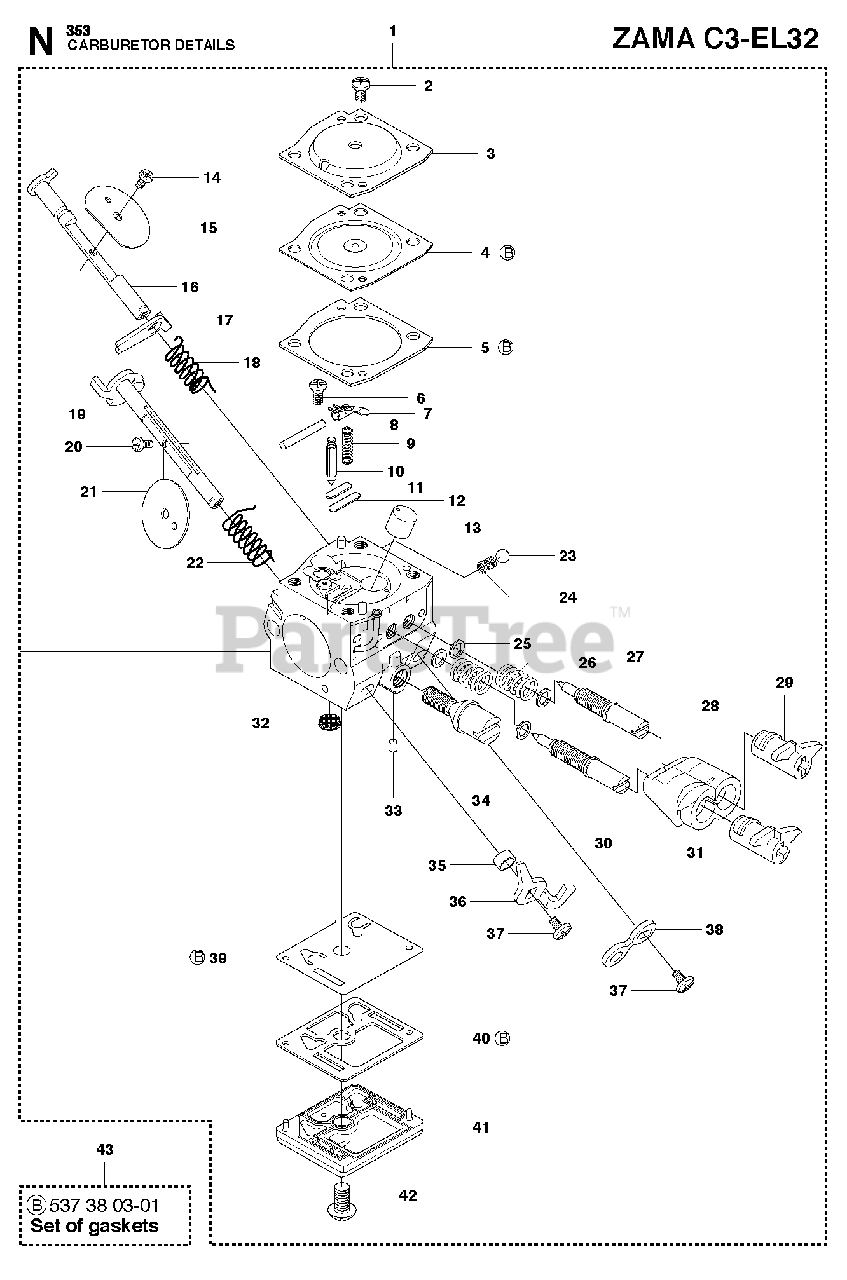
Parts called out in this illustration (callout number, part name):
1	CARBURETOR
2	SCREW
3	COVER
4	DIAPHRAGM
5	Gasket
6	SCREW
7	LEVER
8	PIN FULCRUM
9	SPRING
10	VALVE
11	PLUG
12	PLUG
13	JET
14	SCREW
15	CHOKE FLAP
16	CHOKE SHAFT
17	THROTTLE LOCK
18	SPRING
19	THROTTLE SHAFT
20	SCREW
21	THROTTLE FLAP
22	SPRING
23	BALL
24	SPRING
25	WASHER
26	SPRING
27	JET
28	SLEEVE
29	LIMITER CAP
30	LOW SPEED NEEDLE
31	LIMITER CAP
32	STRAINER
33	PLUG
34	IDLE SCREW
35	BUSHING
36	LEVER
37	SCREW
38	LEVER
39	PUMP DIAPHRAGM
40	GASKET
41	COVER
42	SCREW
43	GASKET SET
